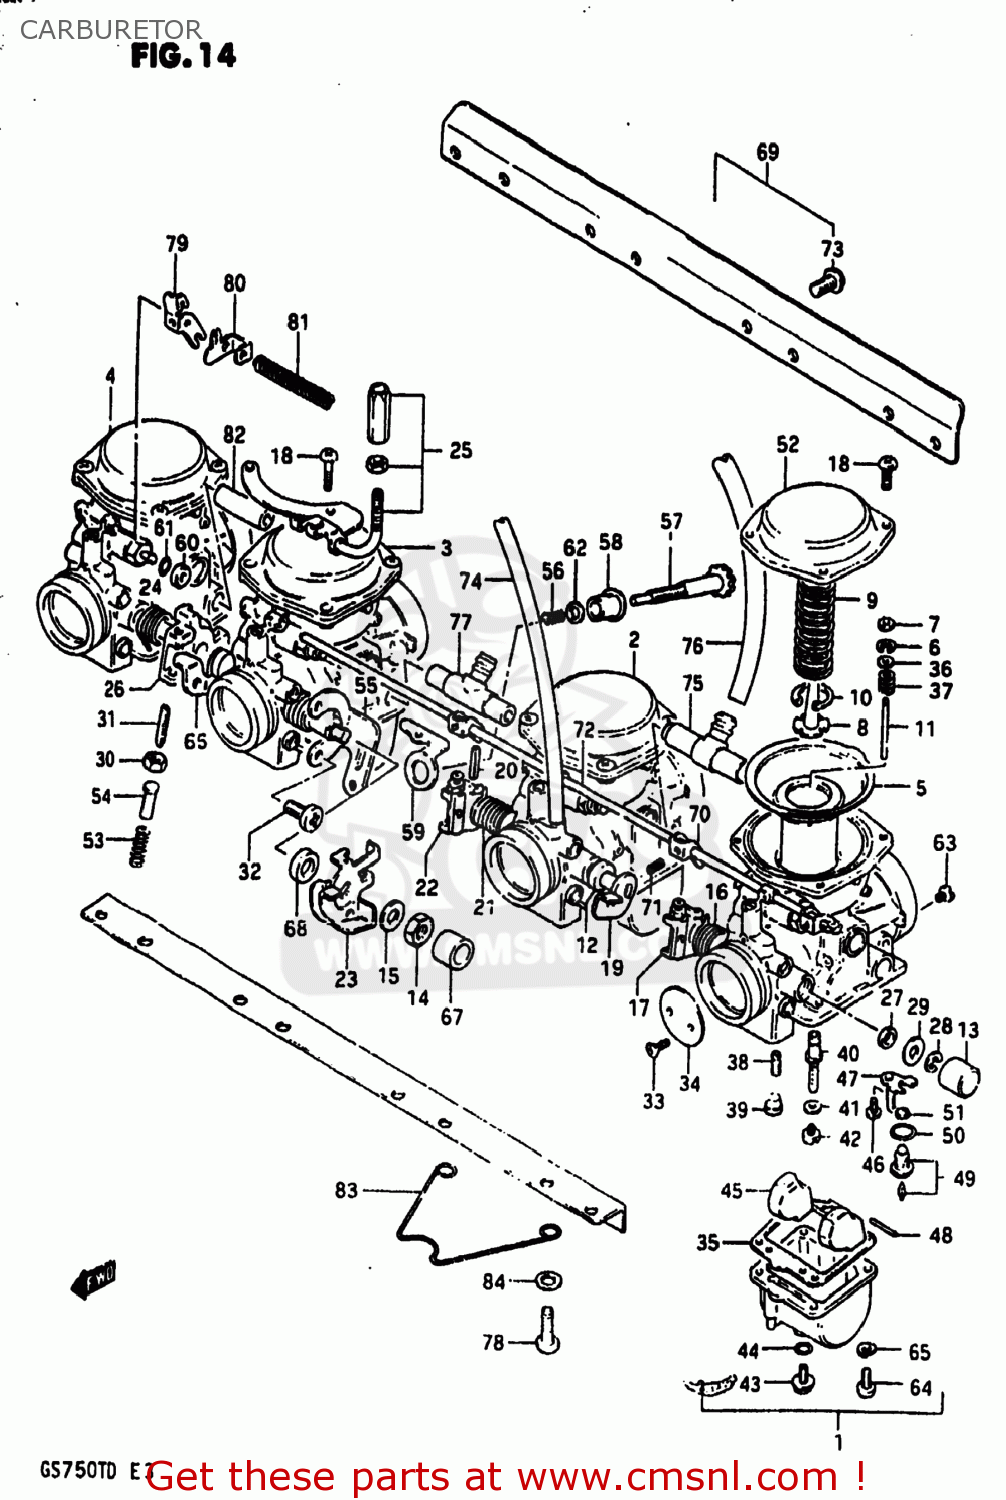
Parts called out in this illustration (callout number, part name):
1	CARBURETOR ASSEMBLY
2	CARBURETOR ASSEMBLY
3	CARBURETOR ASSEMBLY
4	CARBURETOR ASSEMBLY
5	DIAPHRAGM
6	CLIP,NEEDLE
7	RING
8	HOLDER,GUIDE
9	SPRING
10	E RING
11	NEEDLE JET
12	GASKET
13	CAP
14	NUT
15	WASHER
16	SPRING,THROTTLE SHAFT
17	SHAFT,THROTTLE
18	SCREW
19	SHAFT,THROTTLE
20	PIN,THROTTLE SHAFT
21	SPRING,THROTTLE SHAFT
22	LEVER,THROTTLE SHAFT
23	LEVER ASSEMBLY,THROTTLE
24	SPRING,THROTTLE SHAFT
25	BRACKET,THROTTLE CABLE
26	SHAFT,THROTTLE
27	SEAL
28	E RING
29	GASKET,THROTTLE SHAFT (NAS)
30	NUT
31	SCREW
32	SCREW
33	SCREW
34	VALVE,THROTTLE
35	GASKET,FLOAT CHAMBER (NAS)
36	WASHER
37	SPRING
38	JET,PILOT(42.5)
39	PLUG,NEEDLE JET
40	JET,NEEDLE
41	WASHER,NEEDLE NOZZLE
42	JET,MAIN(112.5)
43	PLUG,DRAIN
44	GASKET (NAS)
45	FLOAT
46	SCREW 4X6
47	PLATE,NEEDLE VALVE FITING
48	PIN,FLOAT
49	VALVE ASSEMBLY,NEEDLE
50	O-RING,NEEDLE VALVE
51	FILTER
52	COVER,DIAPHRAGM
53	SPRING,THROTTLE SCREW
54	PIN,THROTTLE LEVER
55	BRACKET,THROTTLE ADJUST
56	SPRING
57	SCREW
58	BUSH
59	BRACKET,THROTTLE ADJUST
60	CAP,STARTER VALVE
61	O RING
62	WASHER
63	JET,AIR
64	SCREW
65	LOCK WASHER
66	SHAFT,THROTTLE
67	RING
68	RING
69	CARBURETOR ASSEMBLY
70	LEVER
71	SCREW
72	SHAFT,STARTER
73	SCREW
74	HOSE
75	NIPPLE,CARBURETOR
76	HOSE,CARBURETOR
77	NIPPLE
78	SCREW 6X12
79	LEVER,CHOKE CABLE
80	PLATE,CHOKE CABLE
81	SPRING,CHOKE CABLE
82	NIPPLE
83	CLIP
84	WASHER
